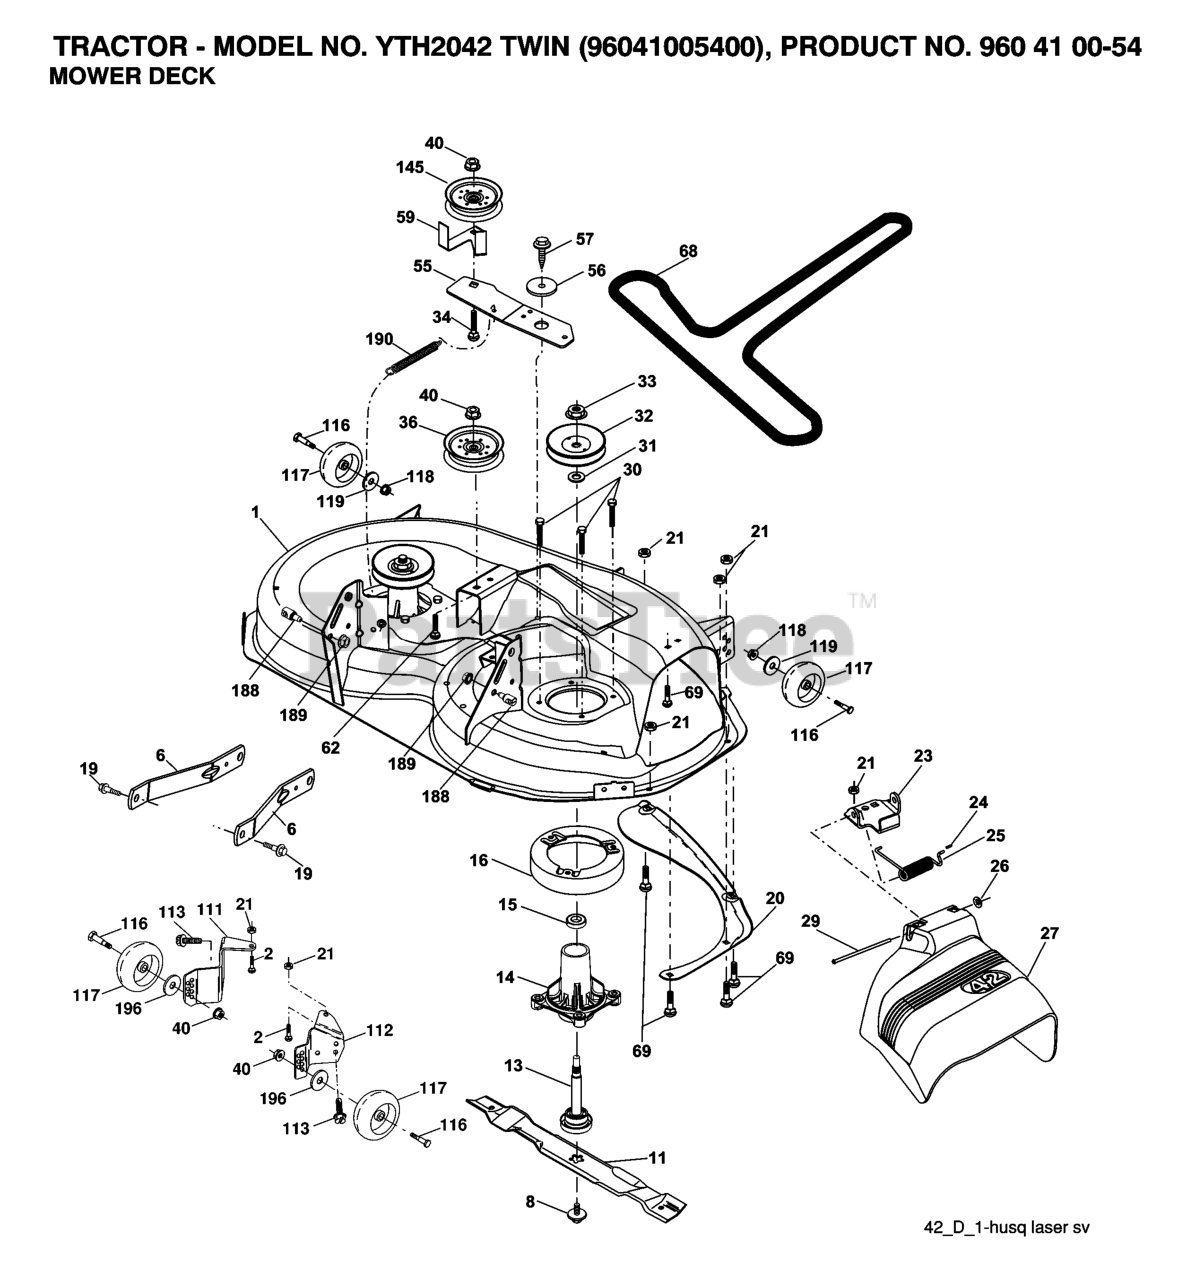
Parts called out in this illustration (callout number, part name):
1	DECK.WELDMENT.42"
2	RP BOLT 5/16-18 X3/4 ZN/YEL GR
6	ARM.SUSPENSION.MOWER.R
8	BOLT.WASHER.ASM.7/16-2
11	42" HI-LIFT BLADE
13	SHAFT.ASM.MDRL.N/GREASE.38
14	RP.HOUSING.MANDREL.4PT.
16	STRIPPER.MANDREL.ROUND.BLACK
19	BOLT.SHOULDER
20	BAFFLE.VORTEX
21	LOCKNUT
23	BRKT.DEFLECTOR.38"2005+
24	CAP-SLEEVE LT
25	SPRING.TORSION.DEFLECT
26	NUT PUSH M
27	SHIELD.DEFLECTOR.MOWER.42"BLAC
29	ROD.HINGE
30	SCREW, WASHER HEAD
31	WASHER.SPACER.MANDREL
32	PULLEY MANDREL
33	NUT.FLANGE.LOCK.TOP
34	BOLT.3/8-16X1.50
36	PULLEY.IDLER.FLAT
40	NUT LOCK FLG 3/8-16 UNC
56	SPACER.RETAINER
57	SCREW 3/8-16X1
59	GUARD, BELT
68	BELT V SECONDARY
69	BOLT
111	BRKT.WHEEL.GAUGE.LH.42"
112	BRKT.WHEEL.GAUGE.RH.42"
113	BOLT.5/16HEX.WHS.HD
116	BOLT M
117	WHEEL.GAGE.HALF.SPOKED
118	LOCKNUT
119	WASHER.5/16.FLAT.STE.STD.
145	PULLEY.IDLER.2006
188	STUD.FASTNER.W/ANTI-ROTATE
189	NUT LOCK HEX FLANGE 5/16-18
190	SPRING.MOWER.DRIVE.ELECTRIC
196	WASHER
